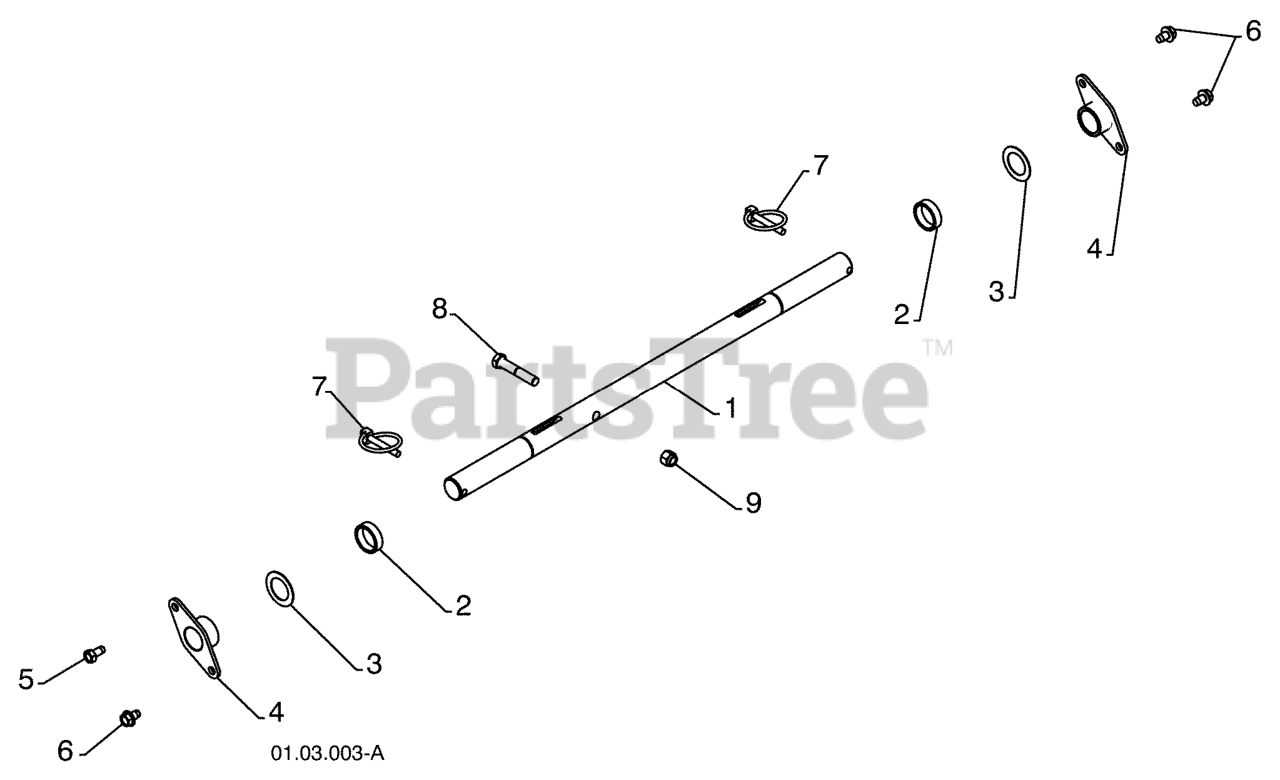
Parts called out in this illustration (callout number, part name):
1	SHAFT.AXLE.POWER.STEERING.HYD
2	SPACER.AXLE.RH
3	WASHER TRUST 1"
4	BEARING, AXLE
6	BOLT 5/16-18 X .500
7	PIN KLIK, 1/4
8	CAP.SCREW.HEX.HD.3/8-16
9	NUT
